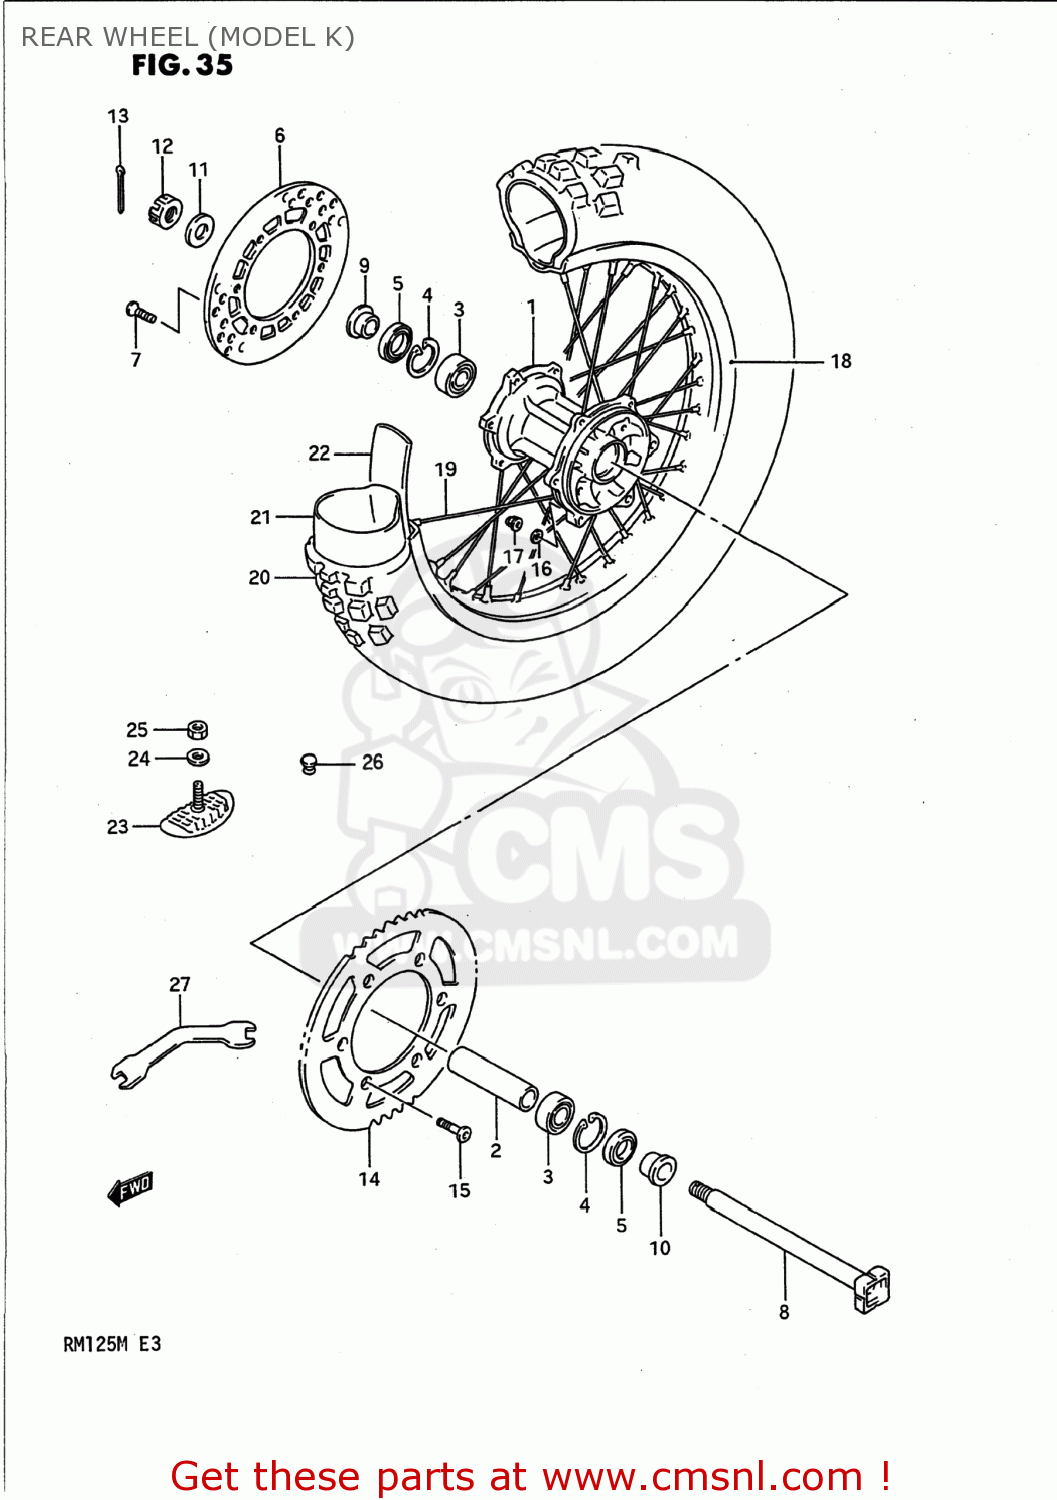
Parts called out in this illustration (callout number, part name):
1	HUB,RR
2	SPACER,RR HUB BEARING
3	BEARING
4	CIRCLIP
5	OIL SEAL
6	DISC,REAR BRAKE
7	SCREW
8	AXLE,RR
9	SPACER,RR AXLE,R
10	SPACER,RR AXLE,L
11	WASHER (19X32X3.2)
12	NUT 18MM
13	PIN,COTTER
14	SPROCKET,REAR
15	SCREW(8X33.5)
16	WASHER
17	NUT
18	RIM,REAR WHEEL (1.85X18 A)
19	SPOKE ASSY,RR WHEEL
20	TIRE COMP,REAR 100/100-1
21	TUBE ASSEMBLY,WHEEL,INNER
22	PROTECTOR
23	STOPPER,BEAD
24	WASHER
25	NUT 8MM
26	CAP(OD:12)
27	SPANNER,OPEN
